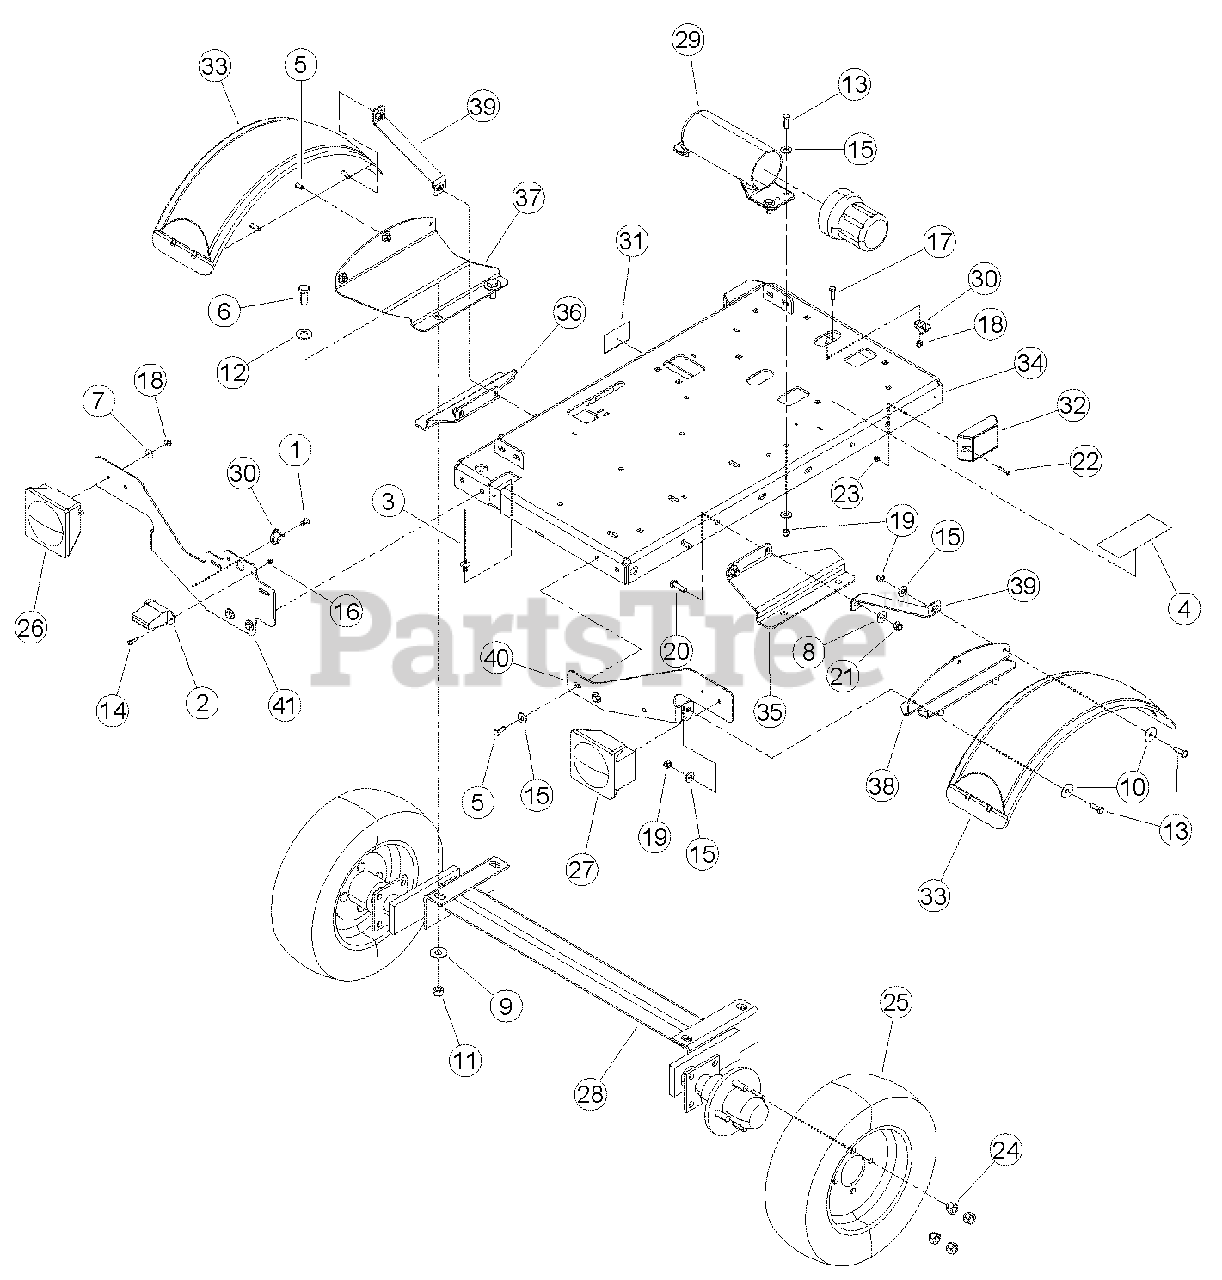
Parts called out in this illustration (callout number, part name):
1	RIVET, 1/4 X 3/4 ST POP
2	LIGHT, LICENSE PLATE
3	TIE, DOME FIR TREE
4	DECAL, MUTILINGUAL MANUAL
5	BOLT, 5/16 X 3/4 HEX HD GR5 ZP
6	BOLT, 1/2 X 1-1/4 HHCS GR5 NC ZP
7	WASHER, 1/4 FLAT ZP
8	WASHER, 3/8 FLAT ZP
9	WASHER, 1/2 FLAT ZP
10	WASHER, 5/16 FENDER ZP
11	NUT, 1/2 CENTERLOCK GRB ZP
12	WASHER 1/2 SAE FLAT ZP
13	BOLT, 5/16 X 1 HHCS GR5 NC ZP
14	SCREW, #10 X 3/4 HEX TAP SC
15	WASHER, 5/16 FLAT ZP
16	NUT, 8-32 NYLOCK
17	BOLT, 1/4 X 1 HEX GR8 ZP
18	NUT, 1/4 NE NYLOCK ZP
19	NUT, 5/16 NE NYLOCK ZP
20	BOLT, 3/8 X 1-1/4 HEX HD GR5 ZP
21	NUT, 3/8 NE NYLOCK ZP
22	MACH. SCREW, 10-24 X 1 RND HD PHL ZP
23	NUT, 10/24 NYLOCK TYPE NM ZP
24	NUT, 1/2-20 WHEEL
25	ASSEMBLY, TIRE + WHEEL 4.80-8
26	LIGHT, LH TAIL
27	LIGHT, RH TAIL
28	AXLE, 1000LB TORSION
29	CONTAINER, MANUAL
30	CLAMP, CABLE MOUNT
31	DECAL, 4.80-8 LOAD RATING
32	LIGHT, AMBER SIDE MARKER
33	FENDER, BLACK PLASTIC DRILLED
34	WELDMENT, CHIPPER TRAILER
35	SUPPORT, AXLE FENDER-RH
36	SUPPORT, AXLE FENDER-LH
37	SHEET, MOUNT FENDER-LH
38	SHEET, MOUNT FENDER-RH
39	BRACKET, FENDER SUPPORT
40	BRACKET, LIGHT RH
41	BRACKET, LIGHT LH
